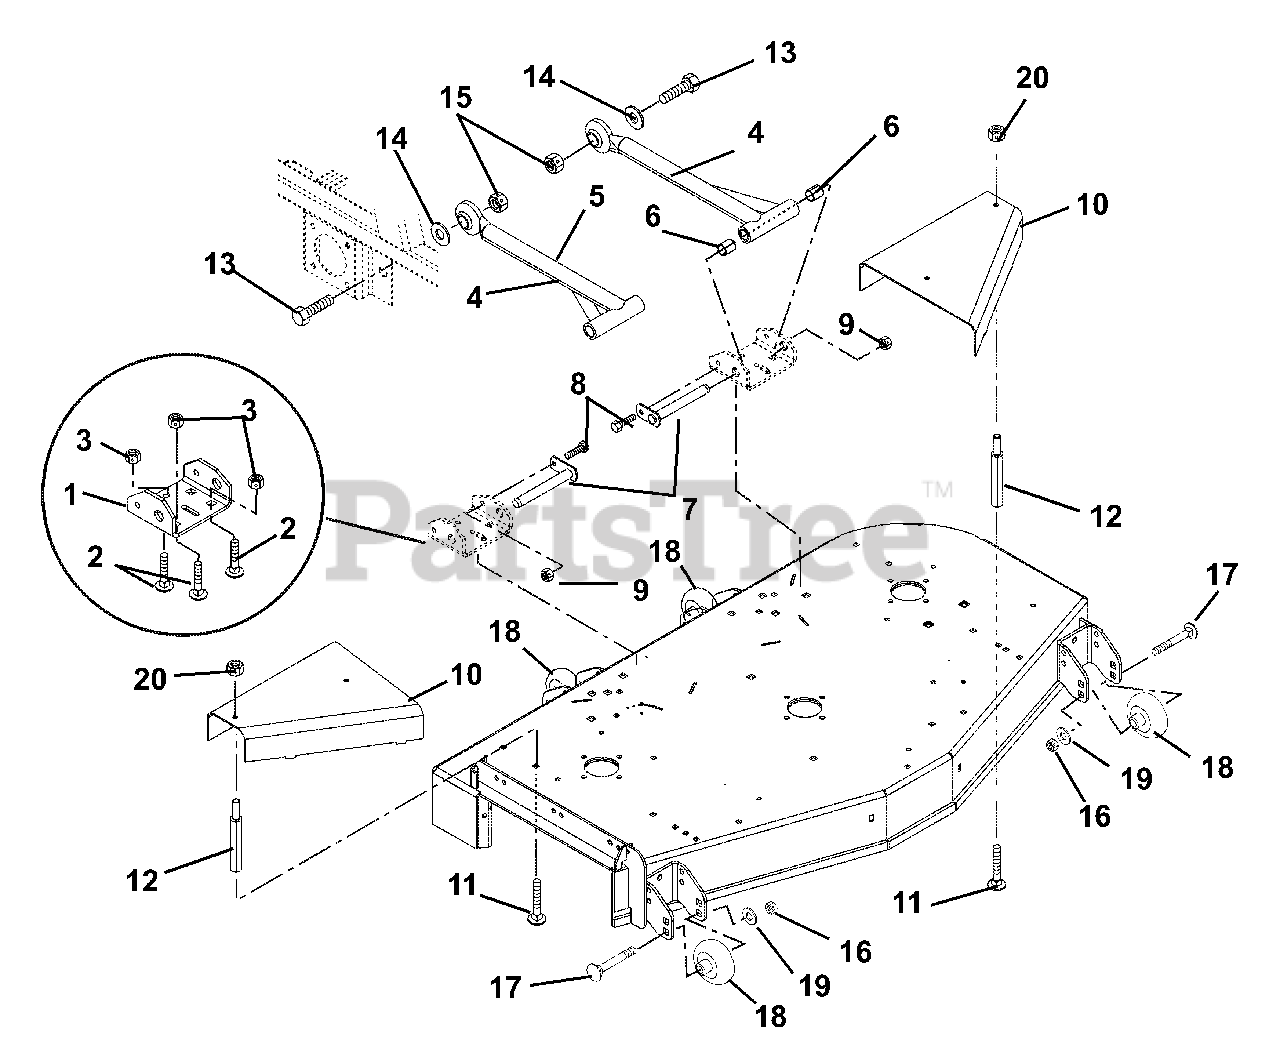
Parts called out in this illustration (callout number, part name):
1	Bracket, Mower Mounting (Rear)
2	Bolt, Round Head Square Neck .50-13 x .75 Grade 5
3	Nut, Locking Center Jam .50-13
4	Assembly, Mower Mounting
5	Mower Mounting Arm
6	Bearing, .75 x .875 x 1.00
7	Weldment, Mower Mounting Pin
8	Bolt-Hex .380-16 x .88
9	Nut, Locking Top Flange .38-16
10	Guard, Pulley
11	Bolt,Round Head Square Neck .31-18 x .75
12	Standoff, 2.75 x 5/16-18
13	Bolt, Hex .875-9 x 3.00
14	Bushing-Sleeve .875 x 1.250 x .531
15	Nut, Locking Center .875-9
16	Nut, Locking Nylon .50-13
17	Bolt, Round Head Square Neck .50-13 x 5.00 Grade 2
18	Wheel, 3 x 5
19	Washer, Flat Steel .531 x 1.06 x .095
20	Nut-Locking-Top-Flange .31-18
